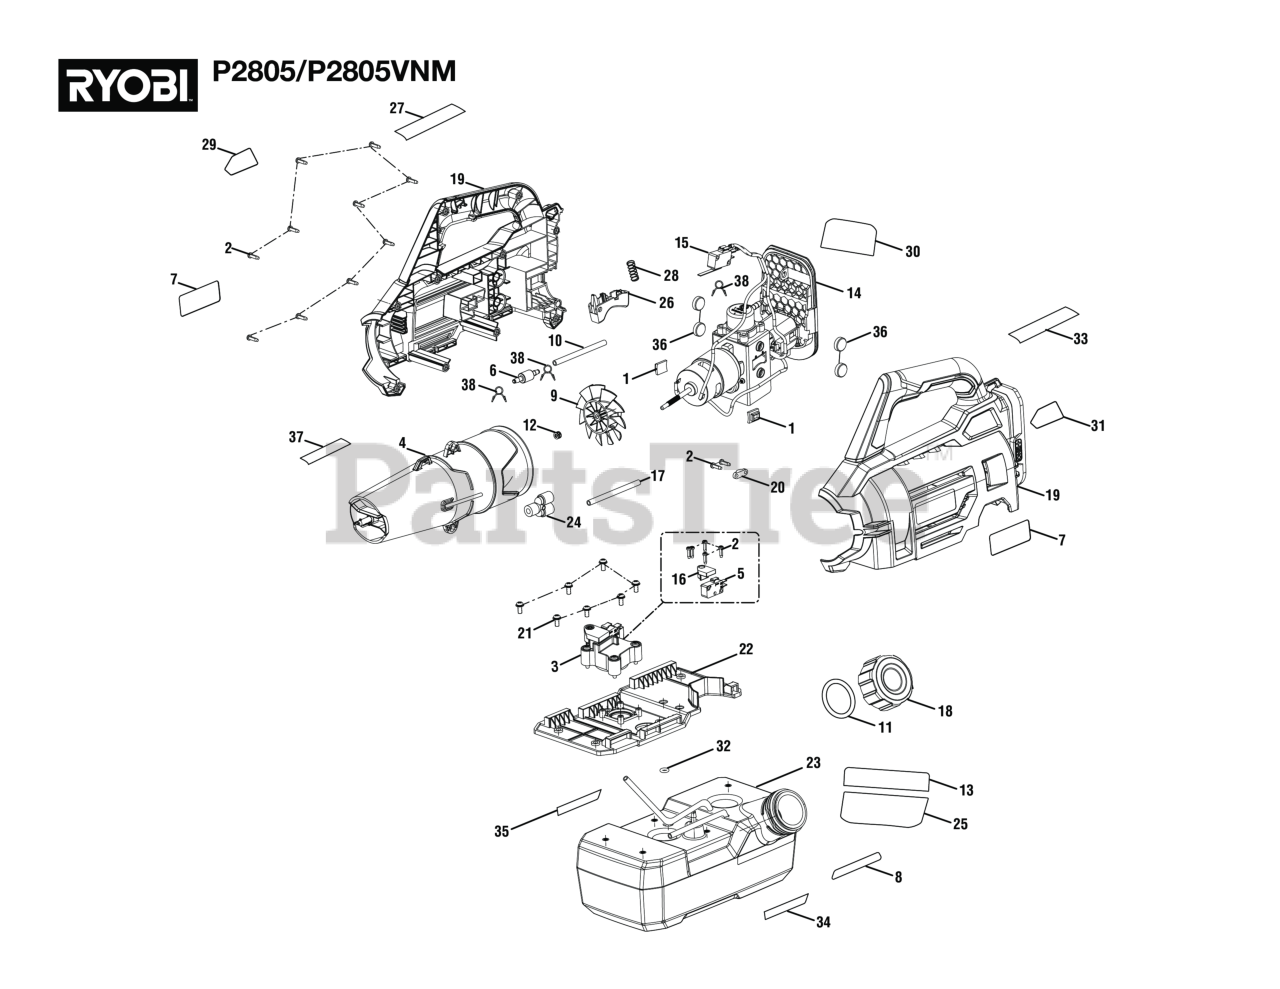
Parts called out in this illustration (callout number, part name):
1	Rubber Plate, EPDM
2	Screw (M4 x 14 mm, T15 Torx Pan Hd.))
3	Pressure Switch Assembly
4	Stator Tube Assembly
5	Pressure Switch
6	Backflow Valve
7	Logo Label
8	Max Fill Label
10	Tube (OD6.35 x ID4.0)
12	Wavy Spring
13	Danger Label
14	Motor, Pump, Switch & Battery Foot Assembly (Inc. Key Nos. 15 & 30)
17	Tube (OD6.35 x ID4.0)
18	Tank Cap Assembly
19	Housing Assembly
20	Cord Clamp
21	Screw w/Lock Washer (M5 x 8 mm, Pan Hd.)
22	Tank Plate
23	Tank Assembly
24	Y Connector
25	Warning Label
26	Switch Trigger
27	Icon Warning Label
28	Compression Spring
29	18 Volt Label (Right)
30	Data Label
31	18 Volt Label (Left)
33	Icon Warning Label
34	Do Not Overfill Label (English)
35	Do Not Overfill Label (French/Spanish)
36	Rubber Cap
37	Defender Label
38	Clip-hose
